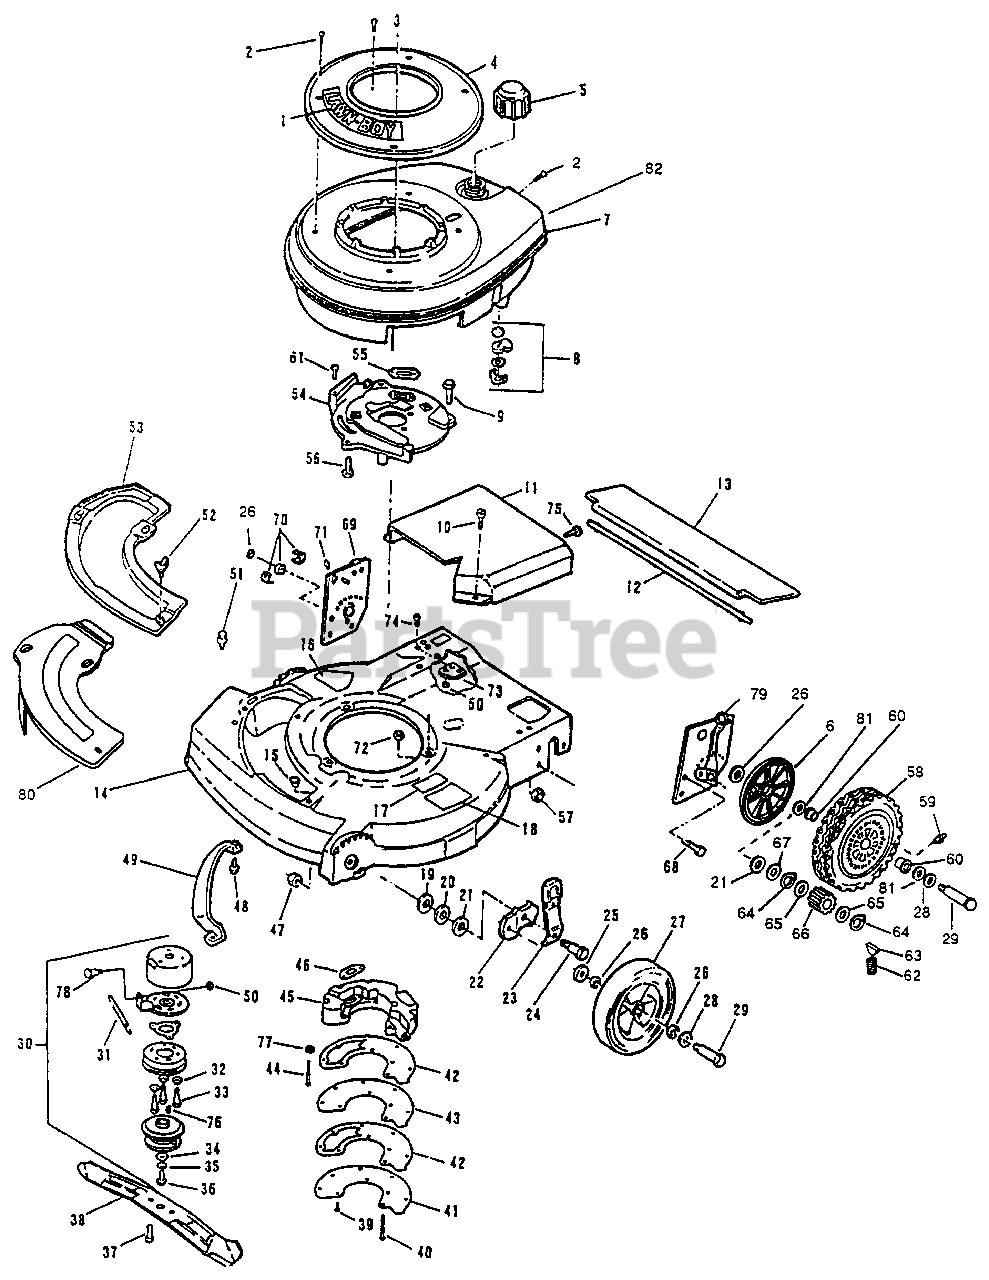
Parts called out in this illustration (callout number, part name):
1	Applique-Starter Base
2	Screw
3	Screw-Starter Mounting
4	Starter Base & Nut Assembly
5	Fuel Cap
6	Cover Wheel
7	Shroud-Engine (Inc. 8)
8	Fuel Shut-Off Assembly
9	Screw-Muffler Plate to Housing
10	Screw-Cover Mounting
11	Cover-Drive
12	Rod-Trailing Shield
13	Shield-Trailing
14	Housing (Inc. 15-18)
15	Grommet
16	Decal-Blade Contact Warning
17	Decal-Starting Pad
18	Pad-Starting
19	Washer
20	Washer-Shim-Wheel Height Adjust Bracket
21	Washer-Shim-Wheel Height Adjust Bracket
22	Bracket-Wheel Height Adjust
23	Knob & Spring Assembly
24	Bolt-Shoulder
25	Washer
26	Washer-Felt
27	Wheel-Front
28	Washer
29	Bolt-Wheel
30	Clutch Brake Assembly
31	Spring
32	Spring Pressure
33	Screw-Shoulder
34	Washer
35	Lockwasher
36	Screw
37	Screw-Sems-Blade
38	Blade-21"
39	Screw
40	Screw
41	Cover
42	Gasket
43	Heat Shield
44	Screw
45	Muffler
46	Gasket
47	Nut
48	Screw
49	Toe Bar
50	Nut-Bolster To Housing
51	Screw-Plate & Chute Mounting
52	Wing Screw
53	Cover Plate
54	Plate-Muffler
55	Gasket-Exhaust
56	Screw
57	Nut
58	Wheel & Tire Assy. (Inc. 59-60)
59	Lube Fitting
60	Bushing-Wheel
61	Screw
62	Spring
63	Key
64	Retaining Ring
65	Spacer
66	Pinion
67	Washer
68	Screw
69	Height Adjuster Assy.-R.H. (Inc. 70-71)
70	Bearing & Retainer Assembly
71	Fitting
72	Nut-Muffler Plate To Housing
73	Bolster-Housing
74	Screw-Bolster to Housing
75	Screw
76	Key
77	Lock Washer
78	Shoulder Bolt
79	Height Adjuster Assy.-L.H. (Inc. 70-71)
80	Mulch Plate Accessory
81	Washer-Felt
82	Decal-Fuel Mix
